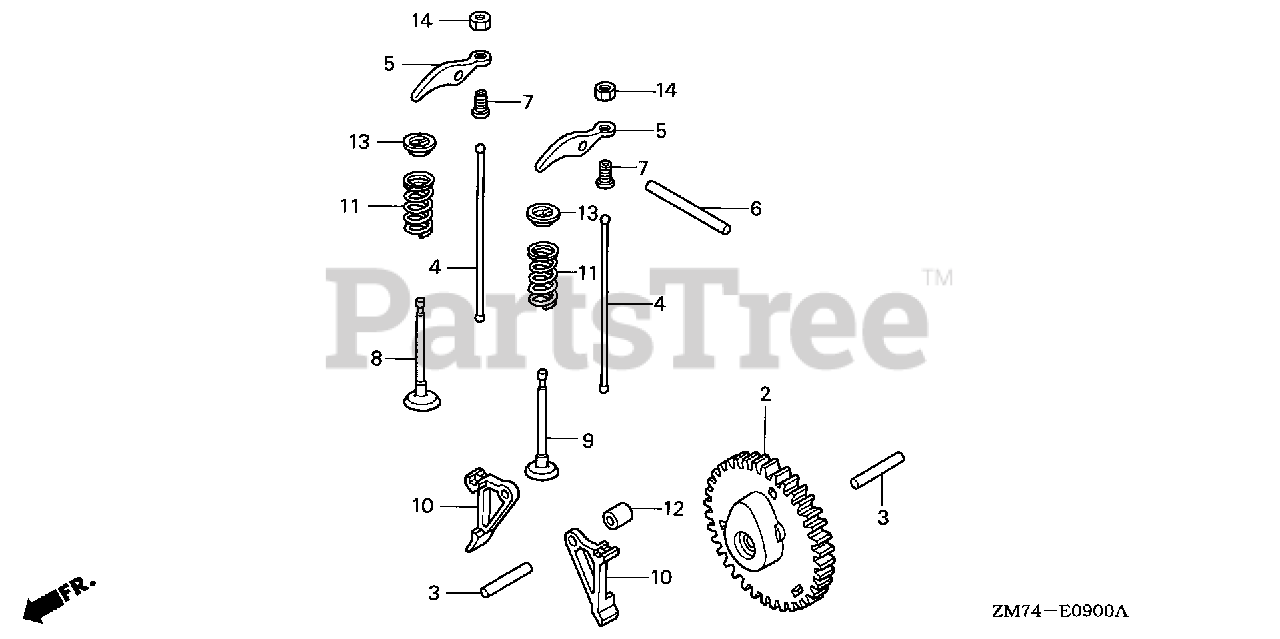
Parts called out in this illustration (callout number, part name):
2	CAMSHAFT ASSY.
3	PIN, OIL PUMP
4	ROD, PUSH
5	ARM, VALVE ROCKER
6	ROLLER (4X37.8)
7	PIVOT, ROCKER ARM
8	VALVE, IN.
9	VALVE, EX.
10	LIFTER, VALVE
11	SPRING, VALVE
12	COLLAR, LIFTER
13	RETAINER, VALVE SPRING
14	NUT, TAPPET ADJ.
